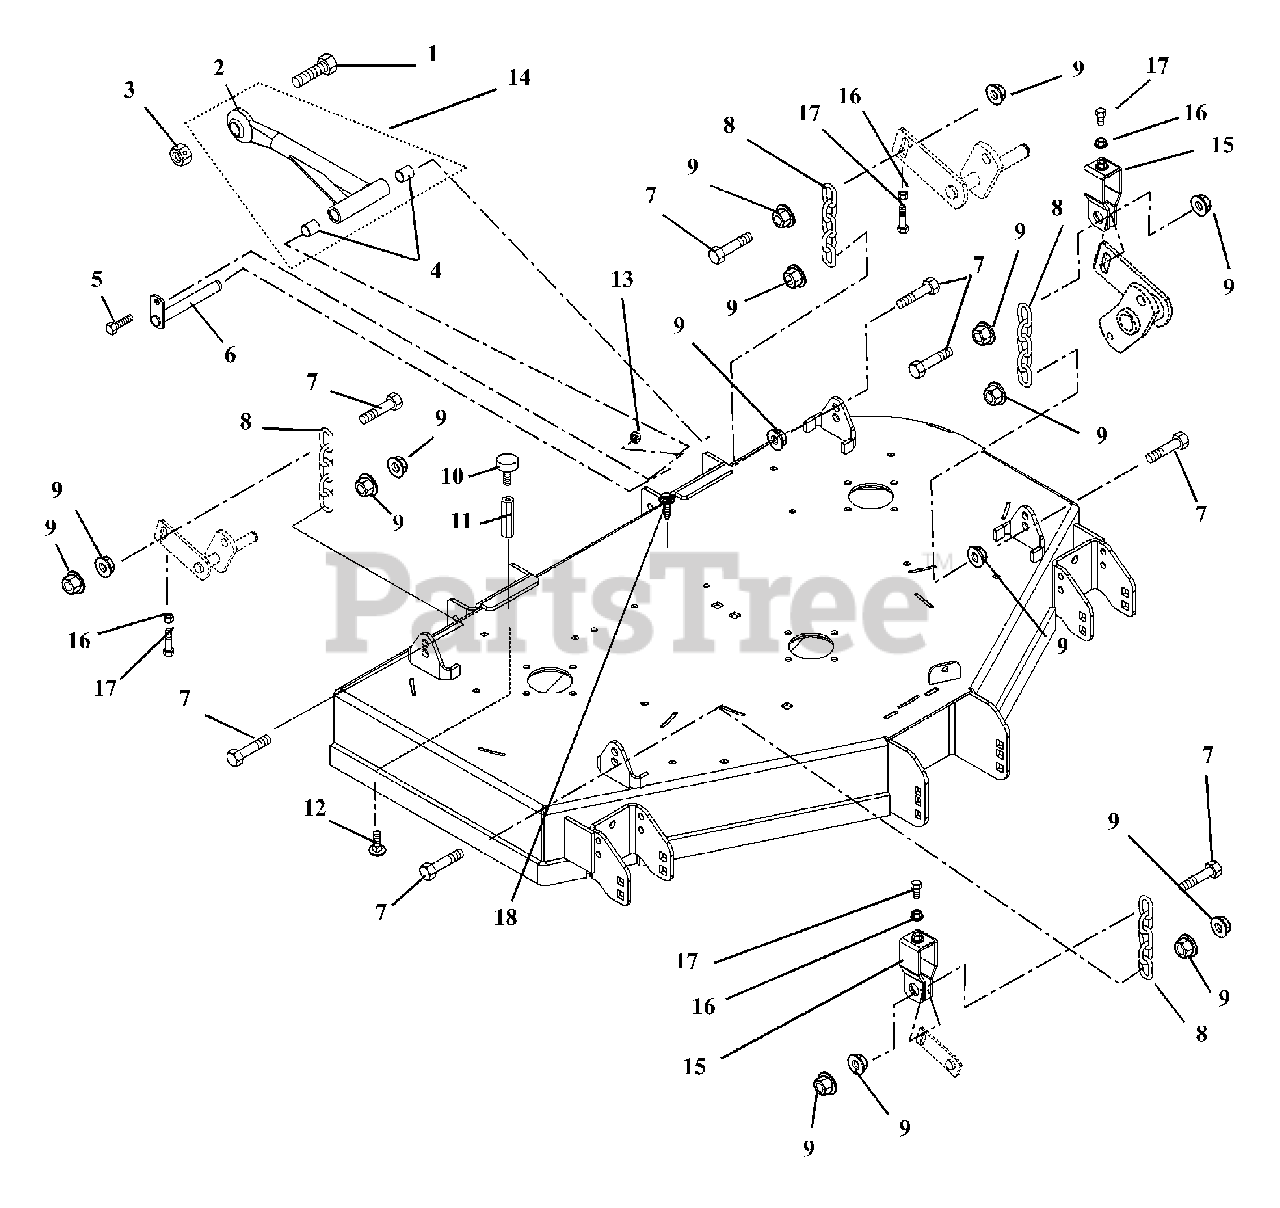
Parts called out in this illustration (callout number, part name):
1	BLT-HEX .875-9X2.75 GR5 YWZC
2	MOWER MOUNTING ARM WMT - BLACK
3	NUT-LK-CTR .875-9 YWZC
4	BRG, .750 X .875 X 1.000
5	@BLT-HEX .38-16X.75 GR5 YWZC
6	WELDMENT, MOWER MTG. PIN
7	BLT, HEX M12-1.75X50 CLS8.8 YZ
8	CHAIN, LINK
9	NUT-SPNLK-FLG M12-1.75 YZ
10	BUMPER, RUBBER
11	NUT, COUPLING .31-18 X 3.00
12	BLT,RDHDSQNK .31-18X.75 LOCTIT
13	@NUT-LK-NYL-FLG .38-16 YWZC
14	ASSM, MOWER MOUNTING ARM
15	BRKT, DECK LEVELING
16	NUT- JAM .312-18 YWZC
17	BLT-HEX .312-18X2.00 FTH GR5YZ
18	@SCR-TAP .38-16X.50 HWH TR YWZ
